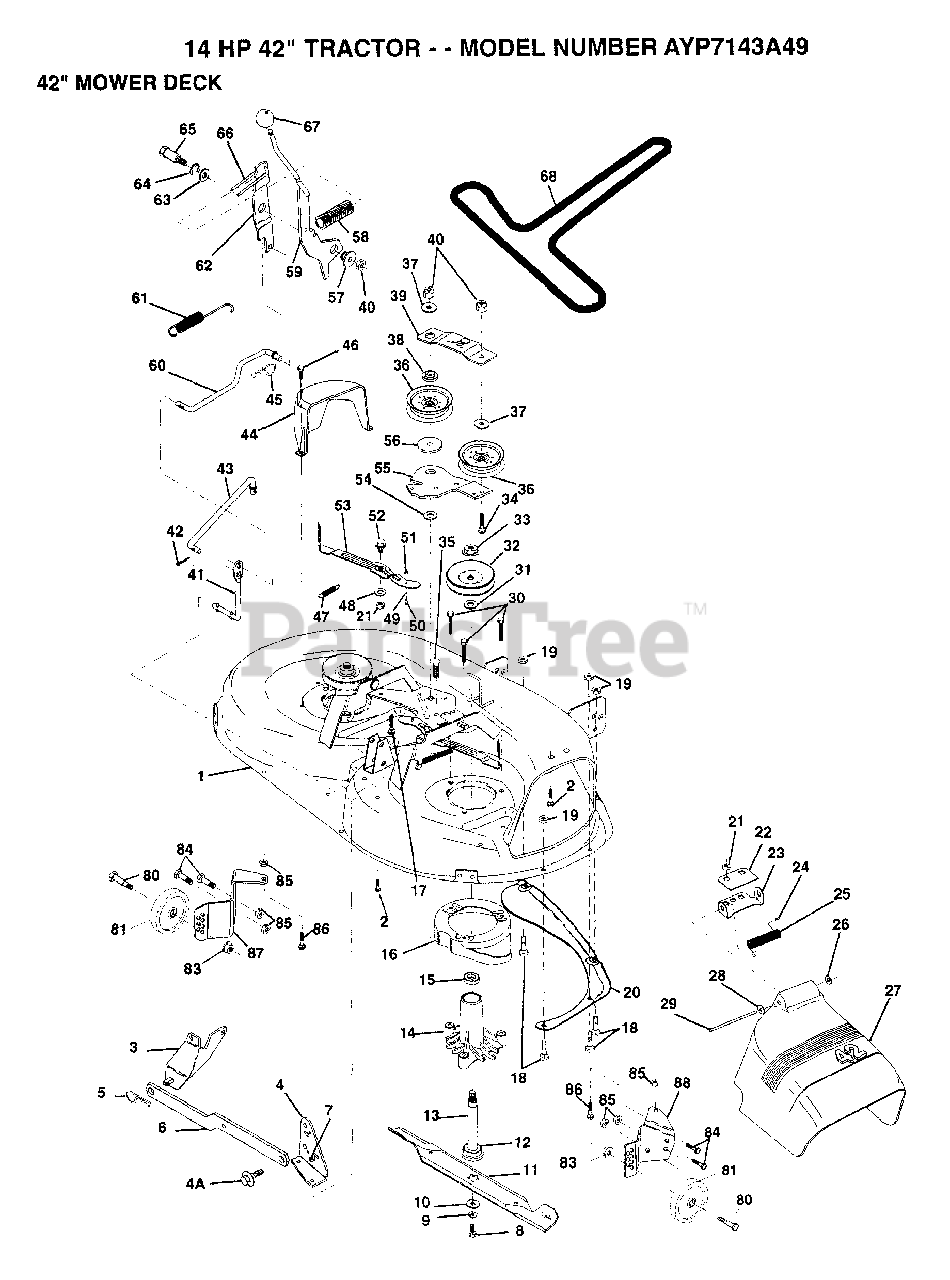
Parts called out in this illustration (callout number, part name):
2	BOLT
3	BRKT ASM SWAY BAR
4	BRKT DECK SW BAR
4A	BOLT SHD 5/16-18
7	NUT
8	BLADE BOLT
10	WASHER.HARD.BLADE
11	"BLADE.42"" MULCHER"
12	BEARING.BALL
14	HSG ASM MANDREL
15	BEARING
17	BOLT CARRIAGE
18	BOLT
19	NUT
22	STIFFENER BRKT
23	DEFLECTOR BRKT
24	CAP-SLEEVE LT
25	SPRING TORSION
26	NUT PUSH M
27	DEFLECTOR.SHIELD
28	WASHER
29	HINGE ROD
31	WASHER
34	BOLT
35	XMAS TREE FASTNER
36	FLAT IDLER PULLEY
37	WASHER GT
38	RETAINER SPACER
39	IDLER ARM STIFF
41	PIVOT ROD
43	CLUTCH ROD SECOND
44	GUARD MAND LH BLK
45	RETAINER M
46	SCREW.1/4-20X5/8
47	SPRING EXTENSION
48	HARD SMALL WASHER
50	SHOULDER BOLT
51	LOCKNUT
52	BOLT.SHLD.5/16-18
53	BRAKE PAD ARM ASM
54	HARDENED WASHER
55	IDLER ARM
56	SPACER RETAINER
57	BUSHING
59	CLUTCH ARM PRI AS
60	"ROD, CLUTCH PRIM"
61	RETURN SPRING
62	CLUTCH ARM SECOND
63	WASHER
64	RING
65	SHOULDER BOLT
66	SPRING KEEPER
67	KNOB T(3/8 HOLE)
68	BELT-V.92.4.MWR
80	BOLT M
81	WHEEL.GAGE.BLK.PL
83	NUT
84	BOLT
